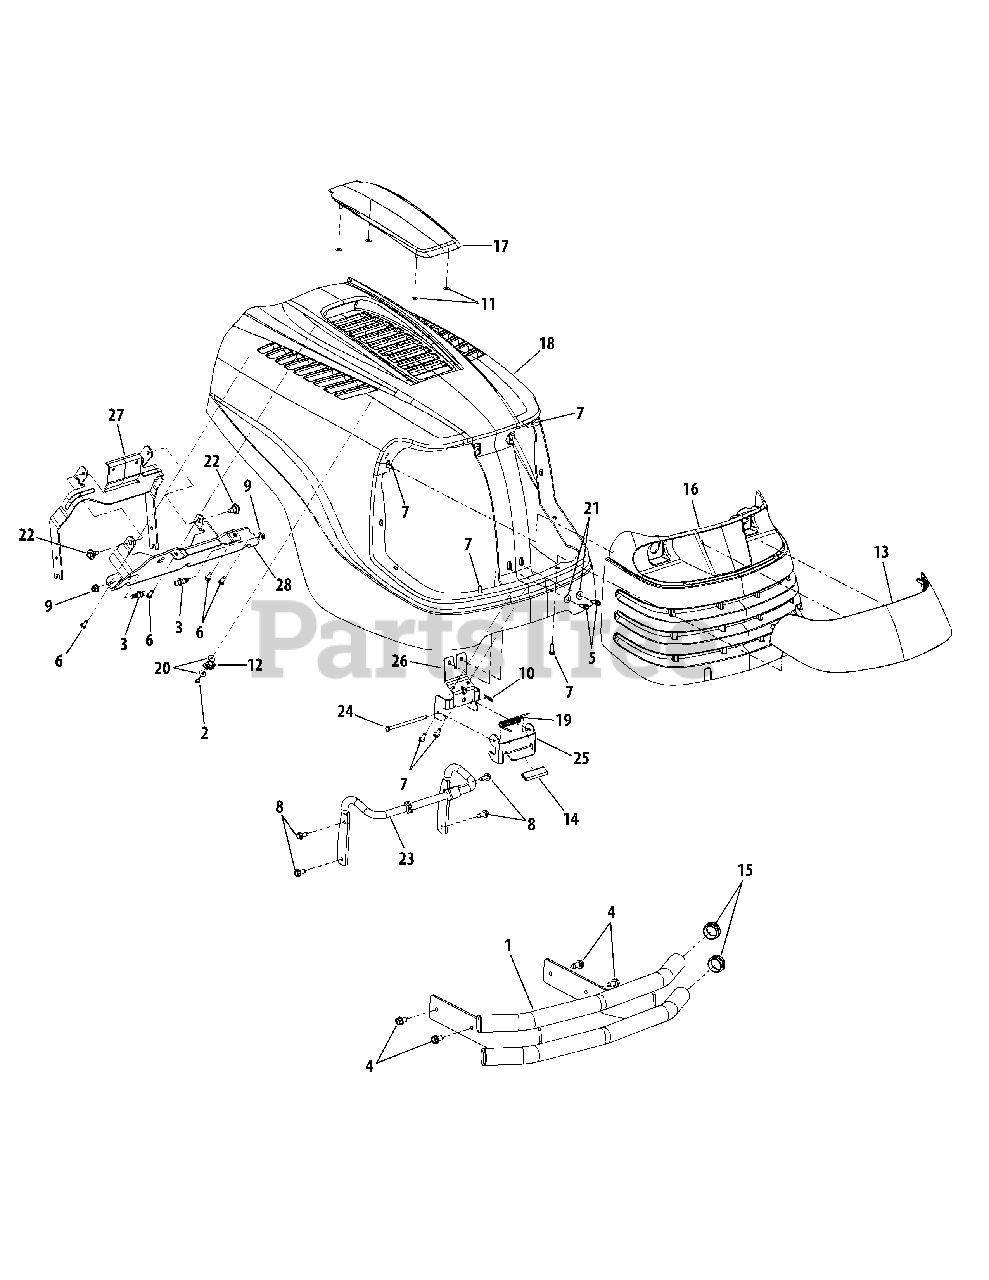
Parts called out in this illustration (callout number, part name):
2	Screw, Hx Wash, Hd. AB, 10-16 x .5
3	Screw, Ball Shoulder, 5/16-18 x.56
4	Screw, Hx Washer Hd Tapp, 3/8-16 x.750
5	Screw, Hx Washer Hd Tapp, 1/4-20 x .750
6	Screw, Hex Cap, 5/16-14 x .75 Gr5
7	Screw, 1/4-15 x.750
8	Screw, Hx Washer Hd Tapp, 5/16- 18 x.750
9	Nut, Flange Lock, 5/16-18 GR5
10	Pin, Cotter,.072 Dia. x 1.13
11	Nut, Push, .25 ID x .50 OD
12	Clamp, 9/16
14	Trim Strip, Vinyl, 2.5 Long
15	Cap, Bumper
17	Cover, Hood
18	Hood
19	Latch Spring
20	Washer, Flat, .194 x .62 x .063
21	Washer, Flat, .26 x .72 x .06
22	Screw, Shoulder, .43 x .29;TT:5/16-18
23	Hood Latch Rod
24	Rod,.250 Dia. x 4.55
25	Latch Pivot Bracket
26	Latch Plate
27	Hood Pivot Bracket
28	Pivot Bracket
